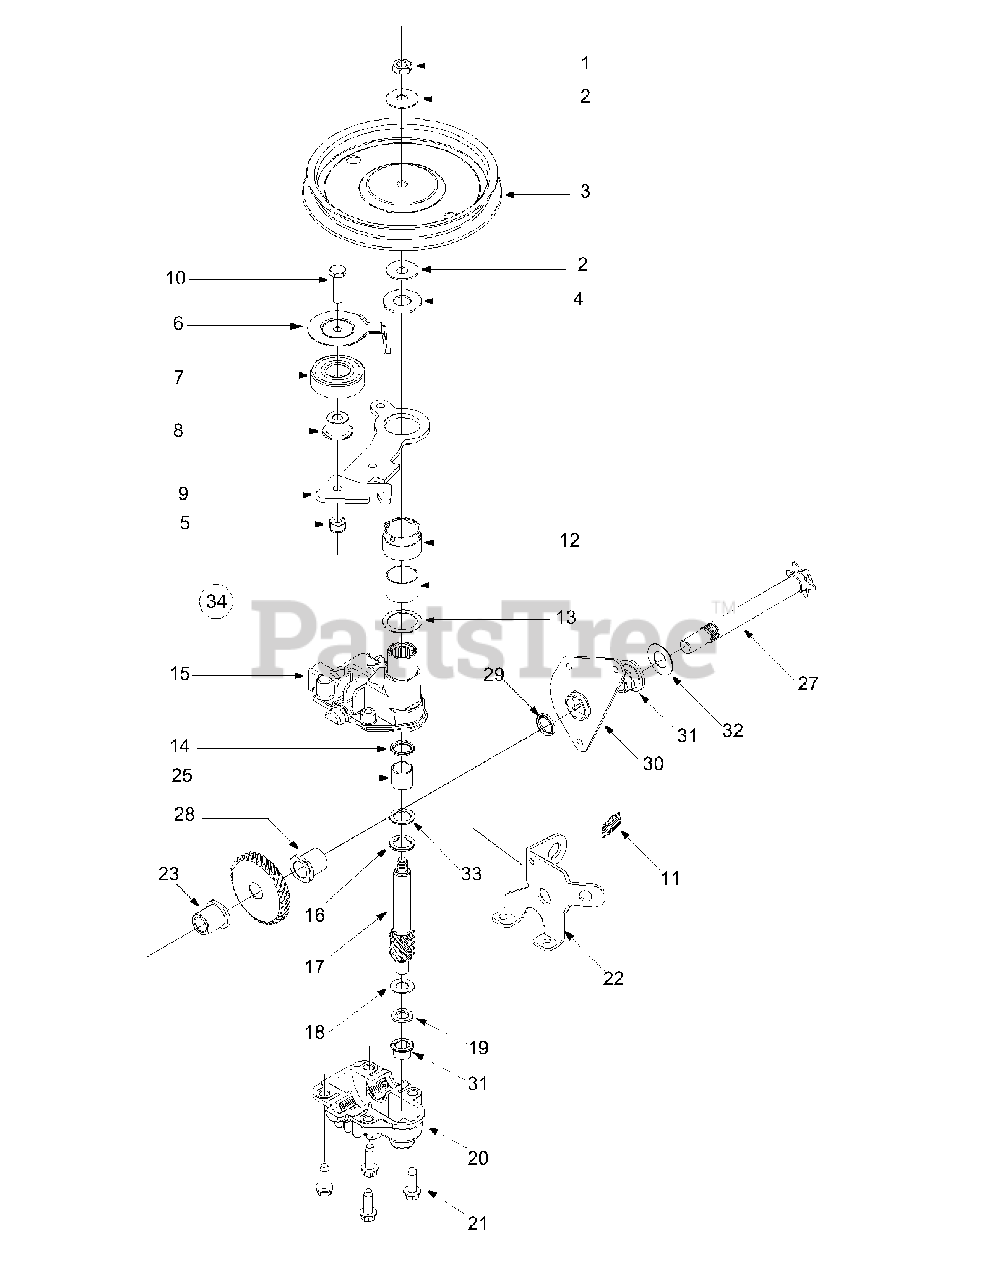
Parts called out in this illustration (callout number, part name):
1	Hex Jam Nut 5/16-24
2	Bell Washer
3	Pulley
4	Flat washer
5	Hex Jam Nut
6	Belt Keeper
7	Bearing
8	Flange Spacer
9	Idler Bracket Assembly
10	Hex Cap Screw
11	Torsion Spring
12	Bearing Sleeve
13	Flat Washer 717-1487
14	Oil Seal
15	Upper Housing Assembly
16	Flat Washer
17	Pinion Shaft 10 T.
18	Thr. Washer
19	Thr. Washer
20	Lower Housing Assembly
21	Hex Screw 1/2-20 x 0.75"
22	Cable Bracket
23	Bearing
24	Shaft Assembly
25	Bearing Sleeve
26	Gear 34 T.
27	Output shaft 6 T.
28	Flange Bearing
29	Oil Seal
30	Pivot Bracket
31	Flange Bearing
32	Flat Washer
33	Thrust Bearing
34	Transmission Assembly Complete
